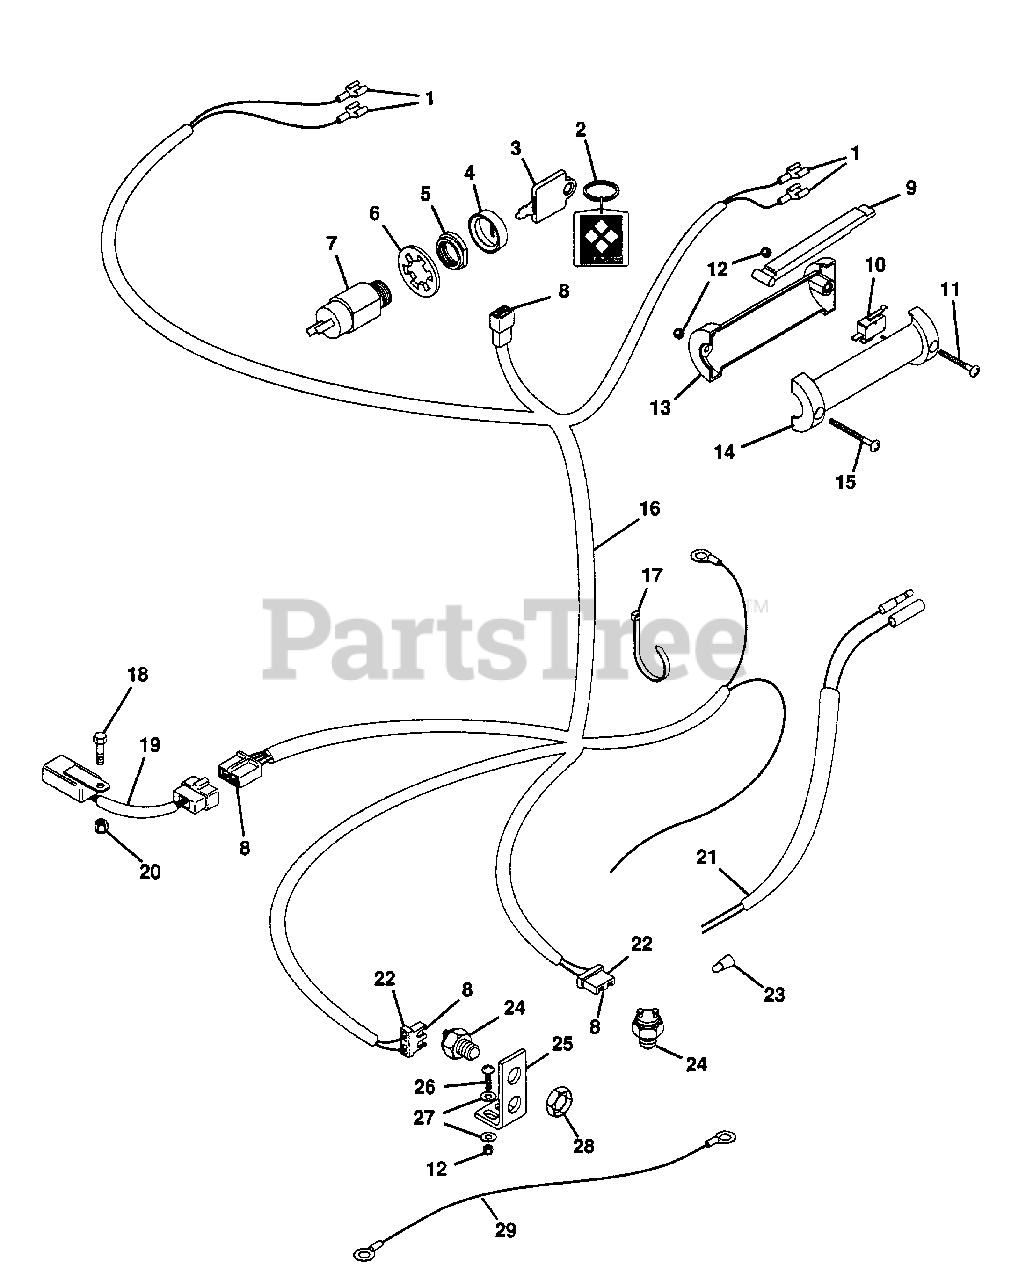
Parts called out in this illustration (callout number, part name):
1	TERMINAL, FEMALE
2	CHAIN, KEY
3	KEY, IGNITION SWITCH
4	BOOT, FOR 9/16 SWITCH
5	NUT, 5/8-32 FOR SWITCH
6	WASHER, LOCK 5/8 INT. TOOTH
7	SWITCH, IGNITION
8	TERMINAL
9	LEVER
10	SWITCH
11	SCREW, MACHINE 10-24X.625 PHD
12	NUT, LOCK 10-24
13	HANDLE, R.H.
14	HANDLE, L.H.
15	SCREW, MACH. 10-24X1.50 PHDCR
16	HARNESS, WIRING
17	TIE, CABLE
18	BOLT, HEX 1/4-20X.750
19	MODULE, INTERLOCK
20	NUT, LOCK 1/4-20
21	WIRE, ENGINE KILL
22	CONNECTOR, 2-WIRE SWITCH
23	NUT, WIRE
24	SWITCH, NEUTRAL START
25	BRACKET, INTERLOCK SWITCH
26	SCREW, MACHINE 10-24X.75 PHD
27	WASHER, FLAT .188X.438X.049
28	NUT, STAMPED 9/16-18
29	WIRE, GROUND
